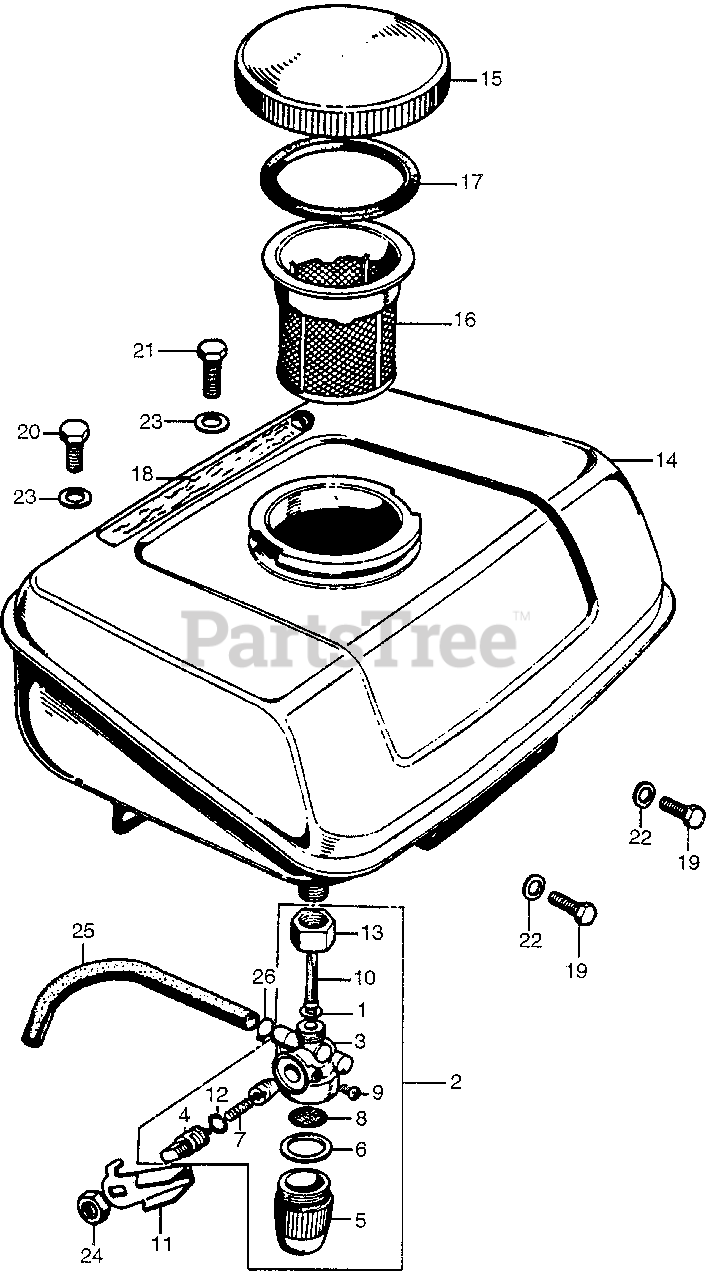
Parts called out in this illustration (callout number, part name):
1	GASKET, STRAINER SETTING (NOT AVAILABLE)
2	PETCOCK ASSY. (NOT AVAILABLE)
3	BODY, PETCOCK
4	LEVER, VALVE
5	CAP, FILTER (NOT AVAILABLE)
6	GASKET, FILTER (NOT AVAILABLE)
7	SPRING, VALUE
8	NET, FILTER (NOT AVAILABLE)
9	SCREW, LEVER FIXING
10	STRAINER (UPPER) (NOT AVAILABLE)
11	LEVER, PETCOCK (NOT AVAILABLE)
12	O-RING, LEVER
13	NUT, TURNBUCKLE (NOT AVAILABLE)
14	TANK, FUEL *PB6M* (CRYSTAL BLUE METALLIC) (NOT AVAILABLE)
14	TANK, FUEL *R8* (BRIGHT RED) (NOT AVAILABLE)
15	CAP, FUEL TANK (NOT AVAILABLE)
16	FILTER, FUEL
17	GASKET, FUEL FILTER (NOT AVAILABLE)
19	BOLT, HEX. (6X12)
20	BOLT, HEX. (8X12)
20	BOLT, HEX. (8X12) (NOT AVAILABLE)
21	BOLT, HEX. (8X20)
22	WASHER, PLAIN (6MM)
23	WASHER, PLAIN (8MM)
24	NUT, HEX. (10MM)
25	BULK HOSE, FUEL (4.5X3000) (4.5)
25	TUBE (4.5X130)
25	BULK HOSE, FUEL (4.5X3000) (4.5X190)
26	CLIP, TUBE (B8)
26	CLIP, TUBE (4.5)
